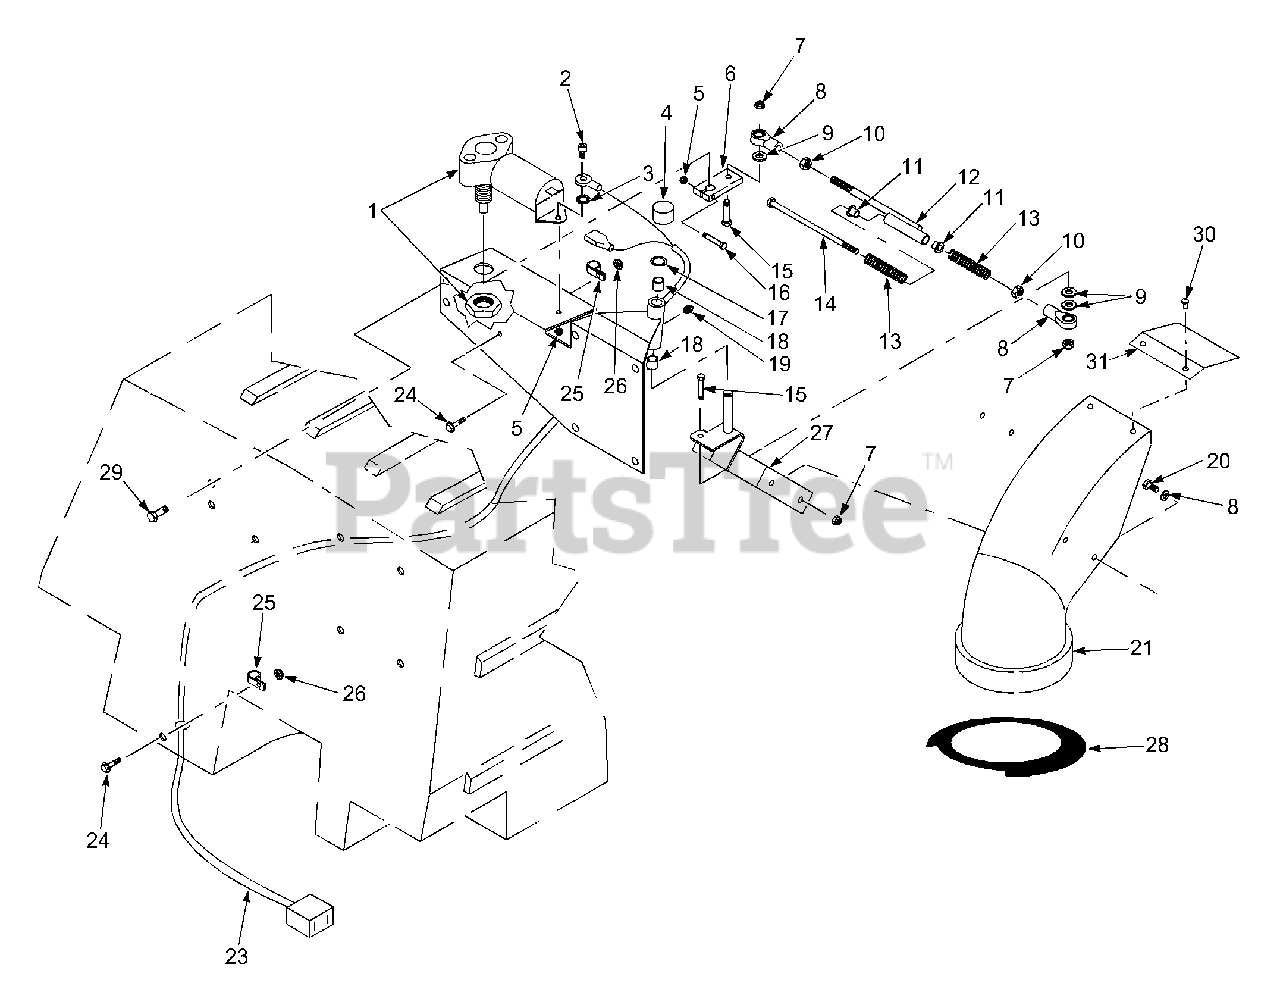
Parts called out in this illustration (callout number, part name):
1	Motor, Actuator
2	Capscrew, Socket Head, #10-32 x 1/2"
3	Washer, External
4	Cap, Plastic
5	Hex Locknut, Elastic Stop, #10-32
6	Lever, Actuator
7	Hex Locknut, Elastic Stop, 5/16-18
8	Rod End, 5/16-24 R.H. Thread
9	Flatwasher, 5/16 (.375 x .875 x .083)
10	Hex Nut, 5/16-18
11	Bushing, Nylon
12	Connecting Rod
13	Spring, Connecting Rod
14	Bolt, Hex Head, 5/16-18 x 7.00"
15	Bolt, Hex Head, 5/16-18 x 1-1/4"
16	Capscrew, Socket Head, #10-32 x 1-1/2"
17	Retainer Ring
18	Bushing, Oilite, .502 ID
19	Grease Fitting
20	Bolt, Hex Head, 5/16-18 x 3/4"
21	Chute
23	Wire Harness, Hopper
24	Bolt, Carr. 1/4-20 x 3/4"
25	Clamp, Cable, 1/2"
26	Serr. Fl. Hex Nut, 1/4-20
27	Pivot, Elbow
28	Seal, Hopper Elbow
29	Body Bolt, 5/16-18 x .81"
31	Deflector, Hopper Chute
